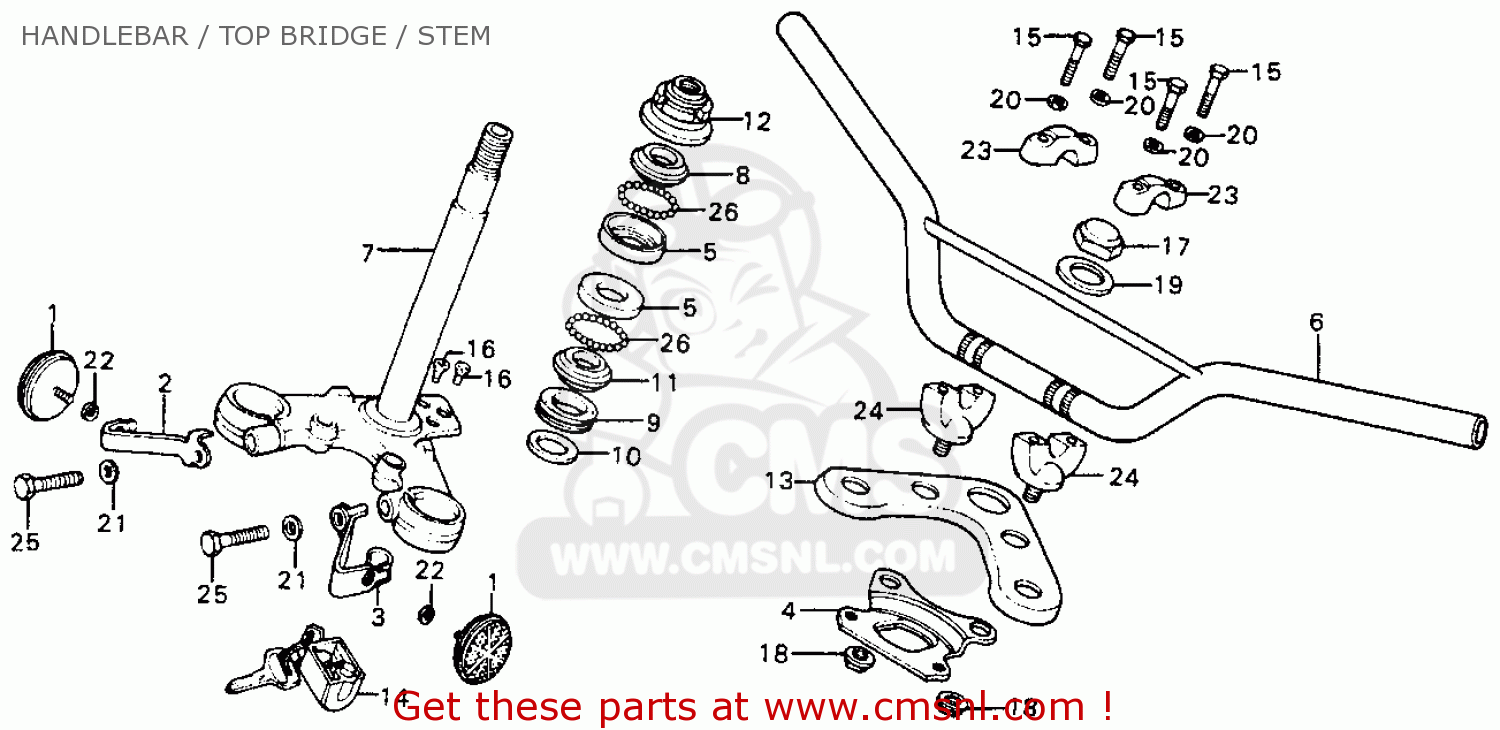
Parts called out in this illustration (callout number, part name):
1	REFLECTOR,REFLEX
2	STAY,R.REFLECTOR
3	STAY,L.REFLECTOR
4	STAY B,METER SET
5	RACE,TOP BALL
6	PIPE,STRG HANDLE
7	STEM, STEERING *NH1*
8	RACE
9	DUST-SEAL
10	WASHER, DUSTSEAL
11	RACE,BOTTOM CONE
12	THREAD,HEAD,TOP,
13	BRIDGE,TOP*NH-105
14	LOCK,STRG.HANDLE
15	BOLT HEX 6X28
16	SCREW, CROSS 6X12
17	NUT A1,STEM
18	NUT,HEX,10MM
19	WASHER,STRG STEM
20	WASHER PLAIN 6MM
21	WASHER,PLAIN,8MM
22	WASHER,SPRING,6MM
23	HOLDER,A2 UPPER
24	HOLDER,B2 UNDER
25	BOLT,HEX.,8X35
26	BALL,STEEL.,6
